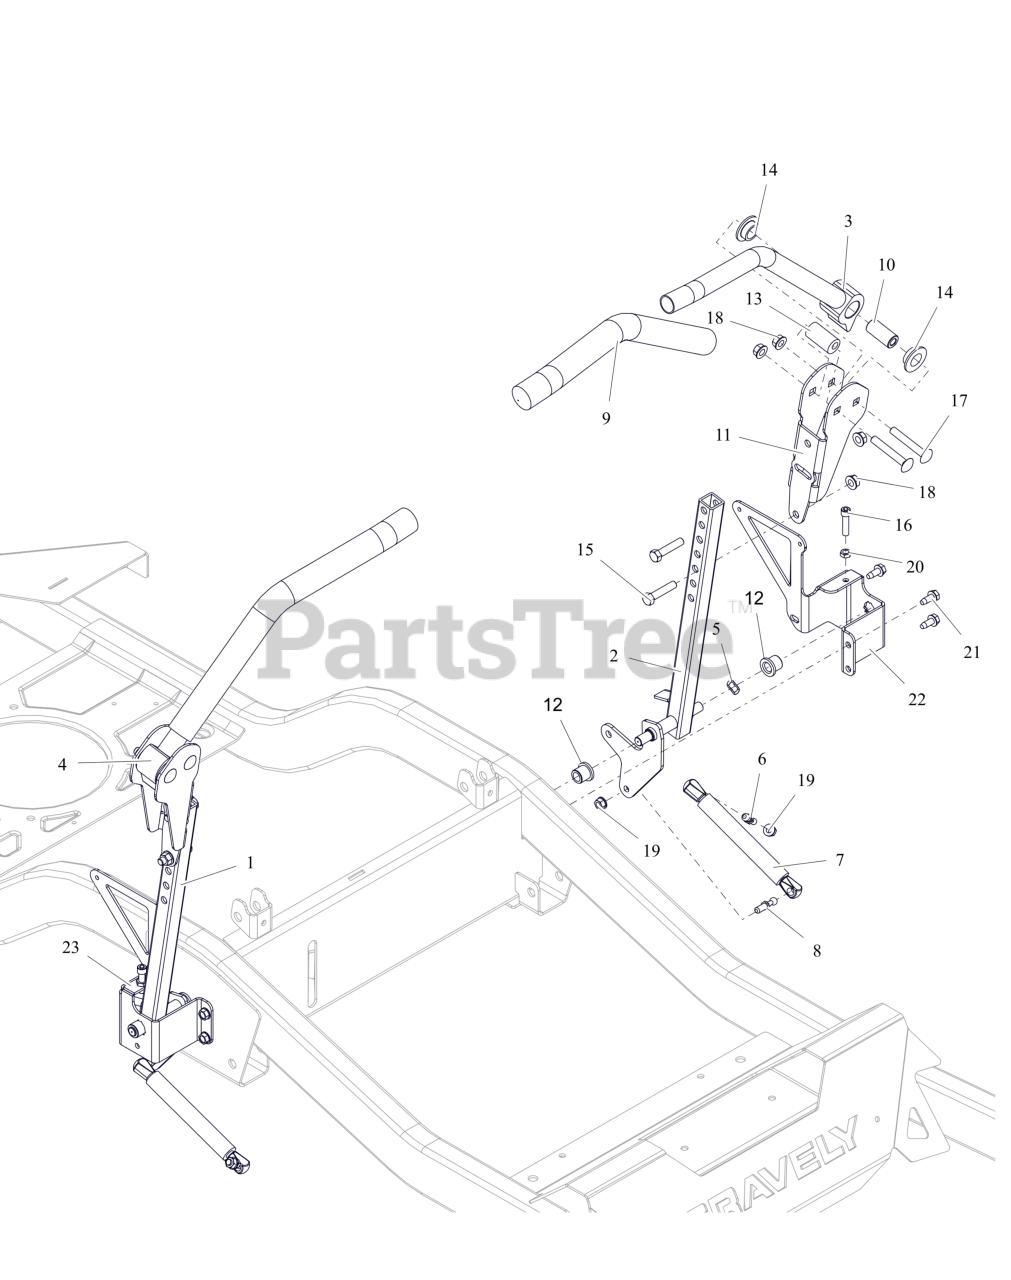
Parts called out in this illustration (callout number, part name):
1	WLDMT, STEERING RH (RED)
2	WLDMT, STEERING -LH (RED)
3	WLDMT, CONTROL HANDLE (RED)
4	WLDMT, CONTROL HANDLE (RED)
5	WAVE WASHER .531X.781X.125FH
6	STUD- BALL
7	DAMPER
8	STUD-BALL-THREADED
9	GRIP, HANDLEBAR
10	SPACER, STEERING ARM
11	BRKT, ADJ UPPER CONTROL ARM (RED)
12	BHSG-FLG .500X.750X.750X.125
13	BSHG, ECCENTRIC.406X.875X1.625
14	BSHG-FLG .762X1.48X.44 NYL
15	BLT, HEX .38-16X1.75 G5 ZCC
16	SCR, SKH .312-18X1.25 GR8 ZC120
17	BLT, RHSSN.38-16X2.50 G5 ZCC
18	NUT-LK-TOP-FLG .38-16 ZC120
19	NUT,LK-CTR-FLG .31-18 GF ZCC
20	NUT-JAM .312-18 G2 ZCC
21	SCR,TAP .312-18X.75 HWH TR ZCC
22	BRKT, STEERING ARM MOUNTING -LH (RED)
23	BRKT, STEERING ARM MOUNTING- RH (RED)
